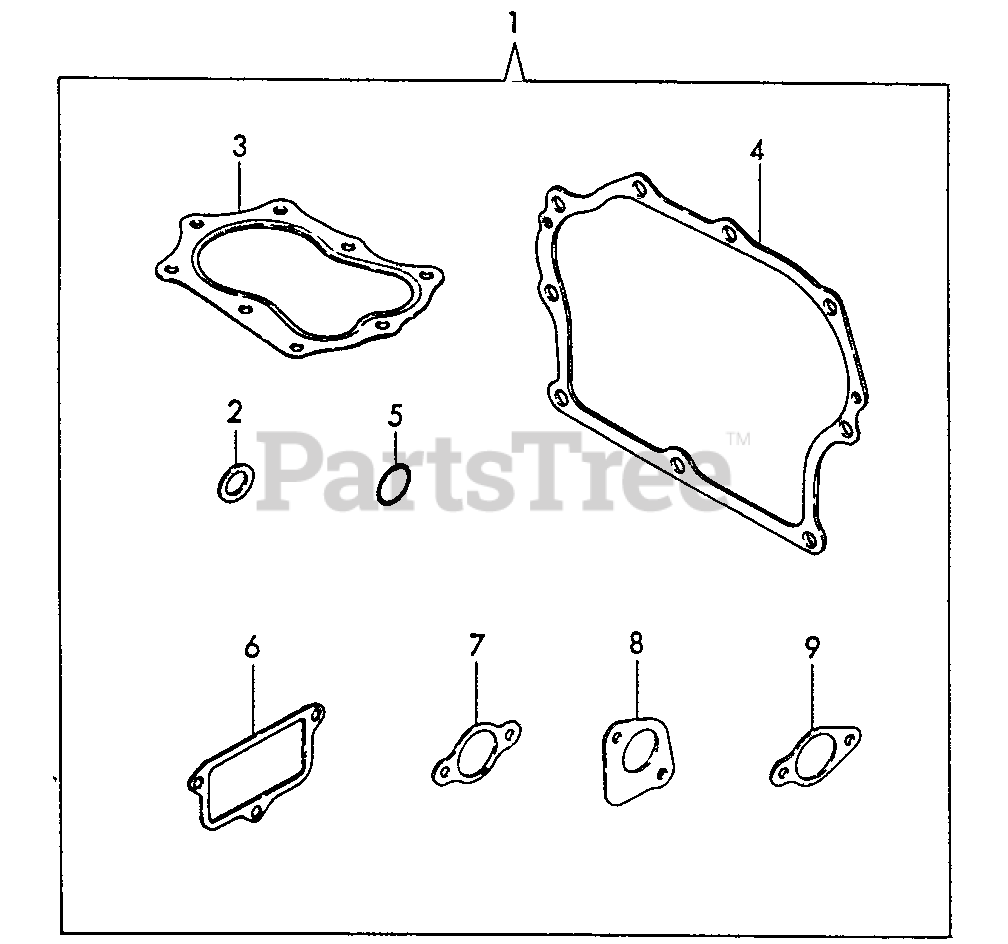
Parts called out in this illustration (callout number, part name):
1	GASKET KIT
2	GASKET
3	GASKET, CYLINDER
4	GASKET, CRANKCASE
5	O-RING 1A P-18.0
7	GASKET, INTAKE
8	GASKET, EXHAUST
9	GASKET
